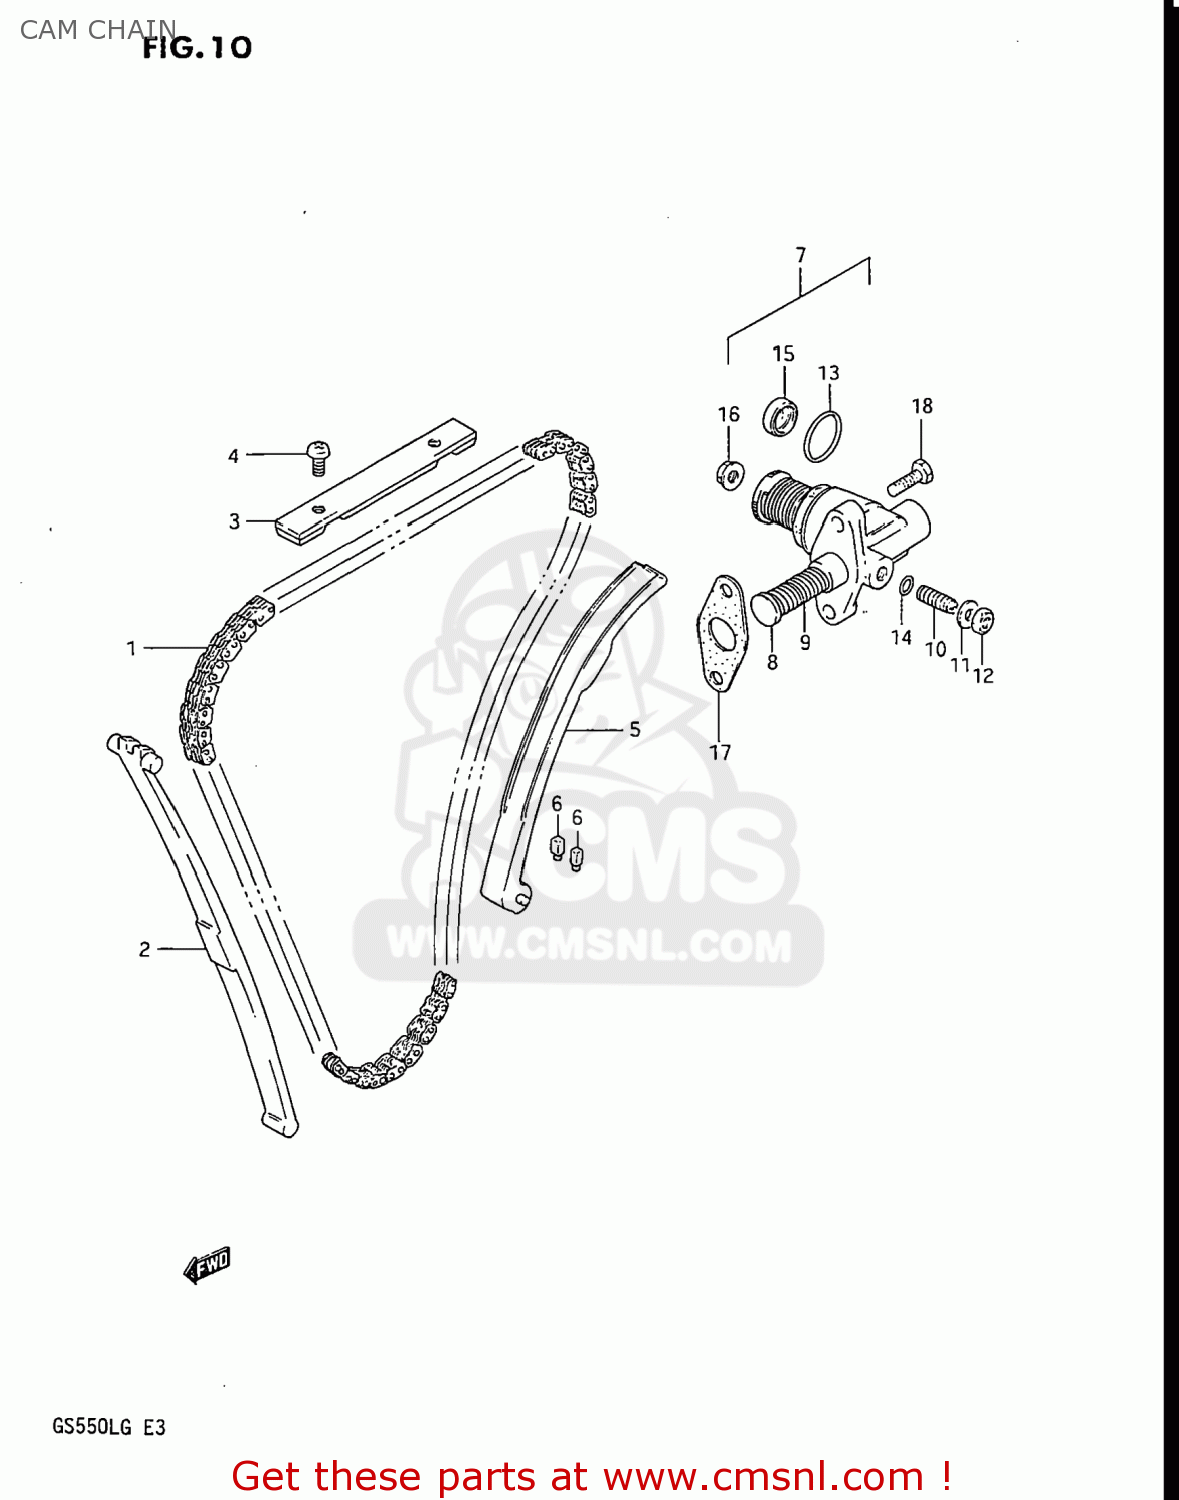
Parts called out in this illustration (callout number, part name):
1	CHAIN,CAMSHAFT DRIVE
2	GUIDE,CAM CHAIN NO.1
3	GUIDE,CAM CHAIN NO.2
4	SCREW
5	TENSIONER,CAM CHAIN
6	CUSHION,CAM CHAIN TENSIONER
7	ADJUSTER ASSY,TENSIONER
8	ROD,PUSH
9	SPRING
10	SCREW,TENSIONER ADJUST
11	WASHER
12	NUT
13	O RING(D:2.4,ID:20.8)
14	O RING(D:1.9,ID:5.7)
15	SEAL,OIL(10X16X4)
16	NUT 6MM
17	GASKET,TENSIONER ADJUSTER (MCA)
18	SCREW
